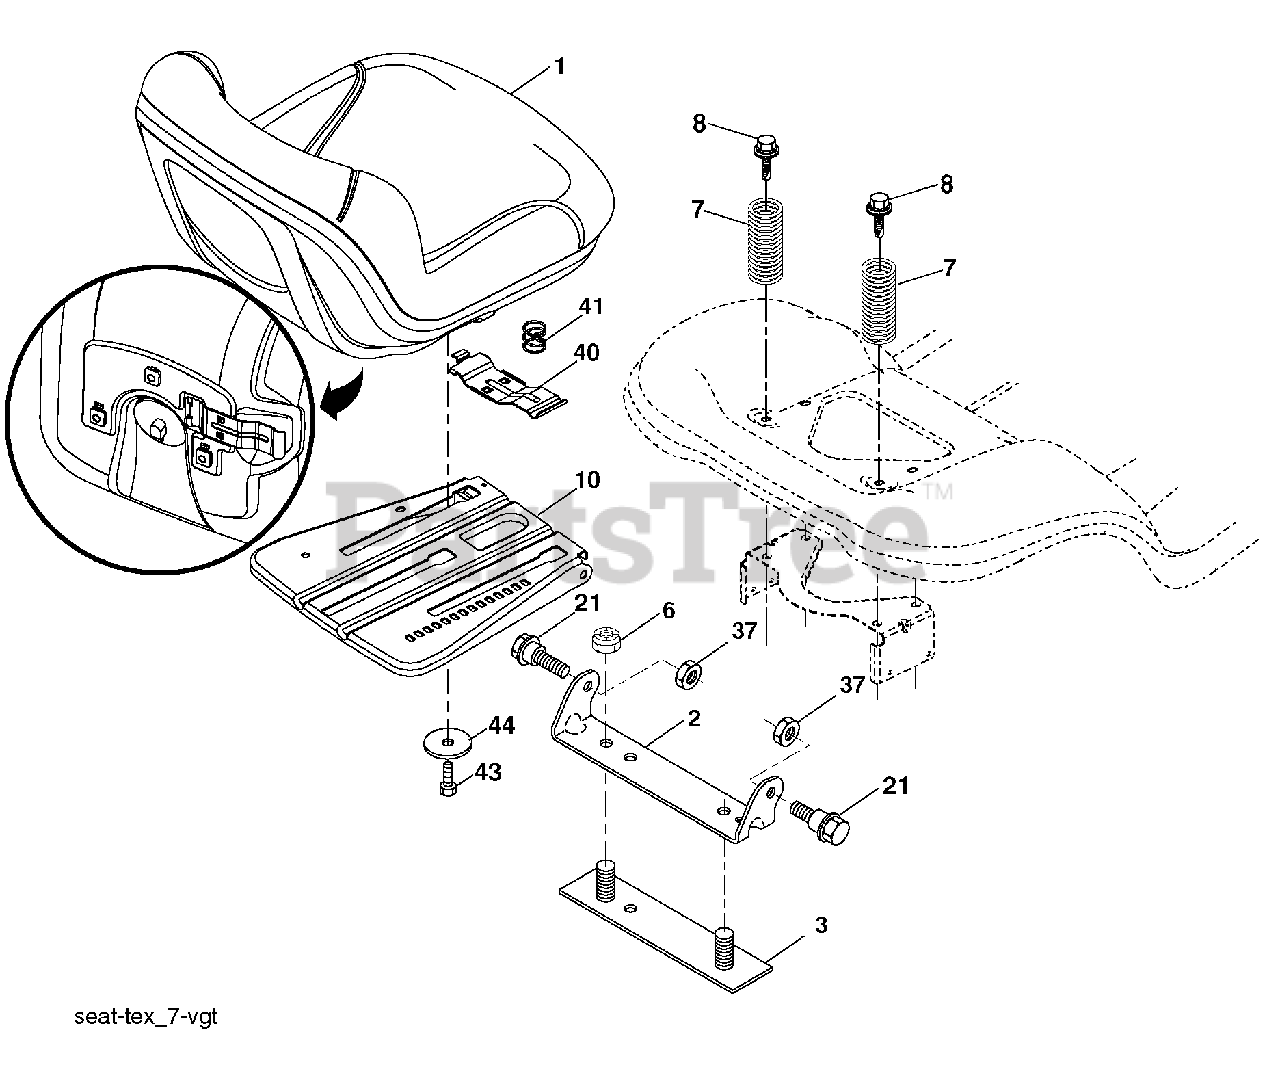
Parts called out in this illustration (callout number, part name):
1	Seat
2	Bracket Pivot Fender
3	Strap, Asm Fender
6	Nut, Lock W/Ins. 3/8-16 unc
7	Spring, Seat Cprsn
8	Bolt 5/16-18 uncx 3/4 w/Sems
10	Pan, Seat
21	Bolt, Shoulder 5/16-18
37	Nut, Lock 5/16-18 unc
40	Handle Slide
41	Spring Latch
43	Bolt 3/8-16 UNC x 3/4
44	Washer 13/32 x 2 3/8 x 12 Ga.
